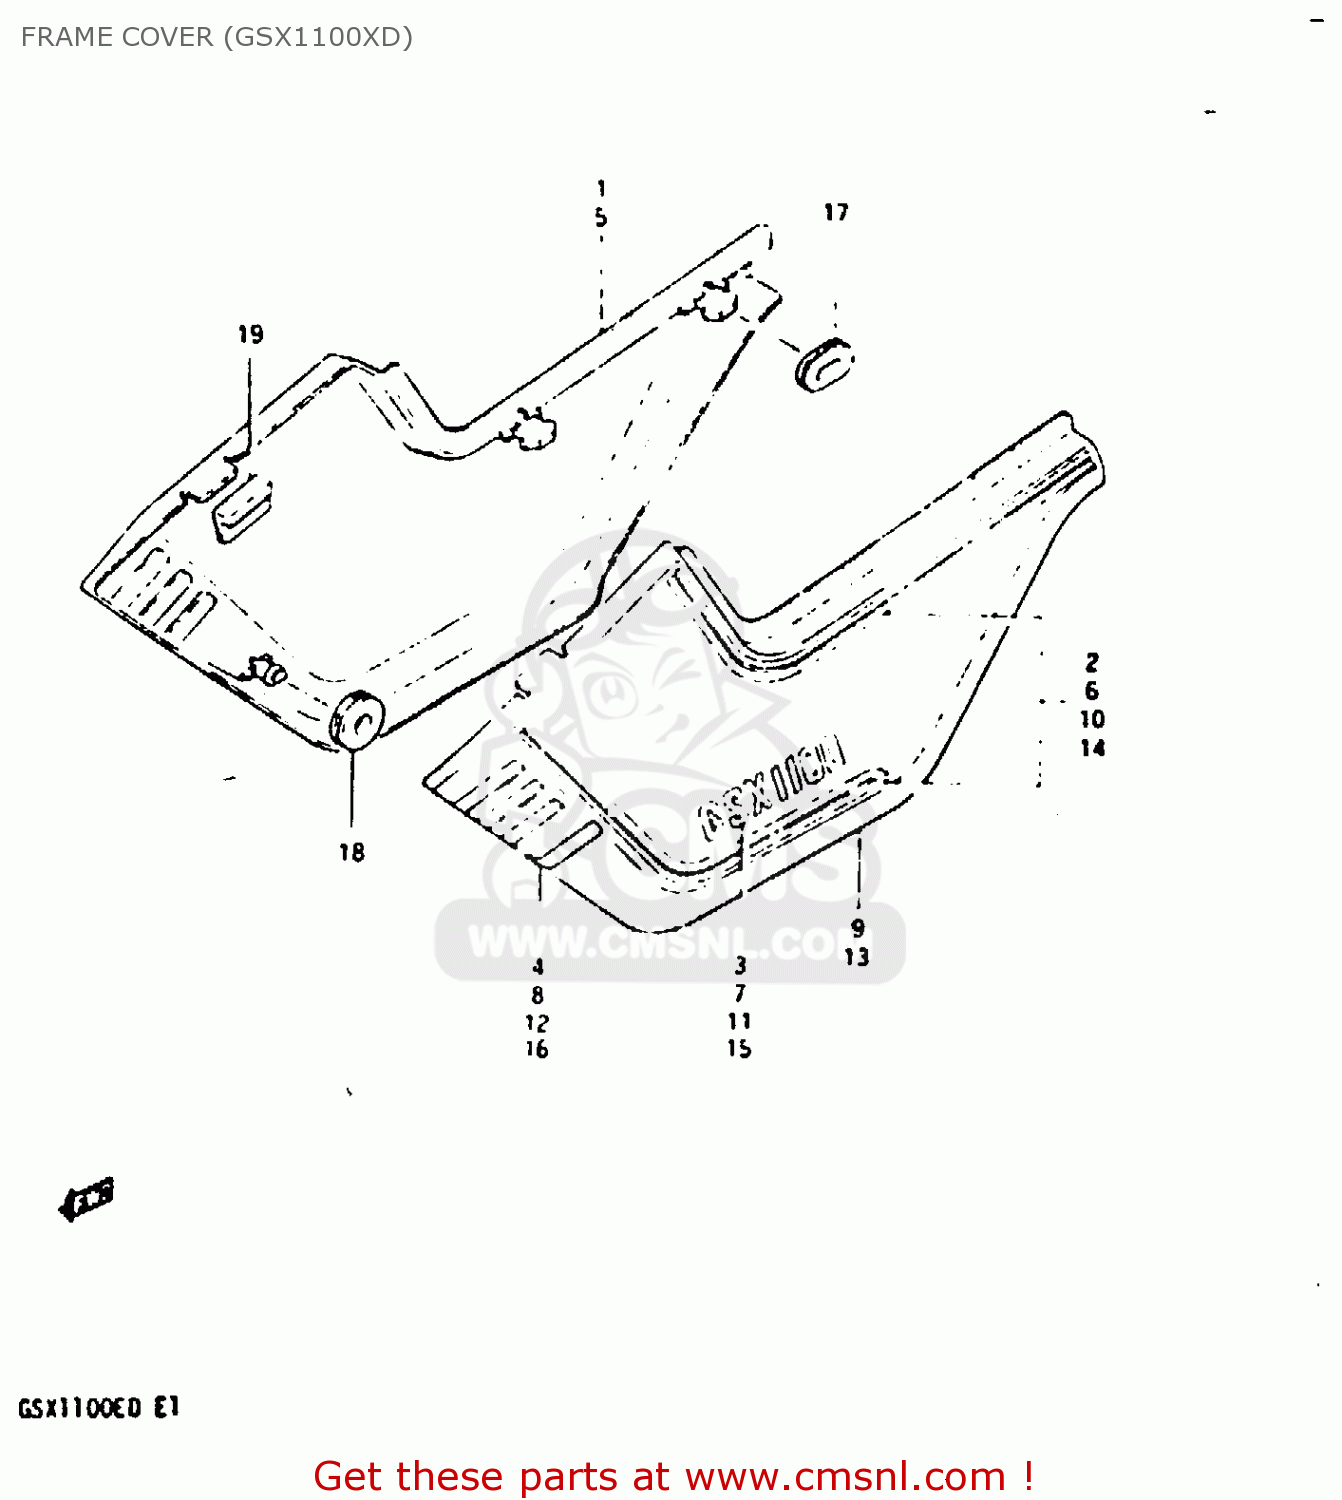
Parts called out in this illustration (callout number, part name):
1	COVER, FRAME RH (BLACK)
2	TAPE SET, FRAME COVER RH
3	EMBLEM, LH (BLACK)
4	LABEL, DENT
5	COVER, FRAME RH (RED)
6	TAPE SET, FRAME COVER RH
7	EMBLEM, LH (BLACK)
8	LABEL, DENT
9	COVER, FRAME LH (BLACK)
10	TAPE SET, FRAME COVER LH
11	EMBLEM, LH (BLACK)
12	EMBLEM,FRAME COVER,CENTER
13	COVER, FRAME LH (RED)
14	TAPE SET, FRAME COVER LH
15	EMBLEM, LH (BLACK)
16	EMBLEM,FRAME COVER,CENTER
17	CUSHION
18	CUSHION
19	CUSHION,FRAME COVER
